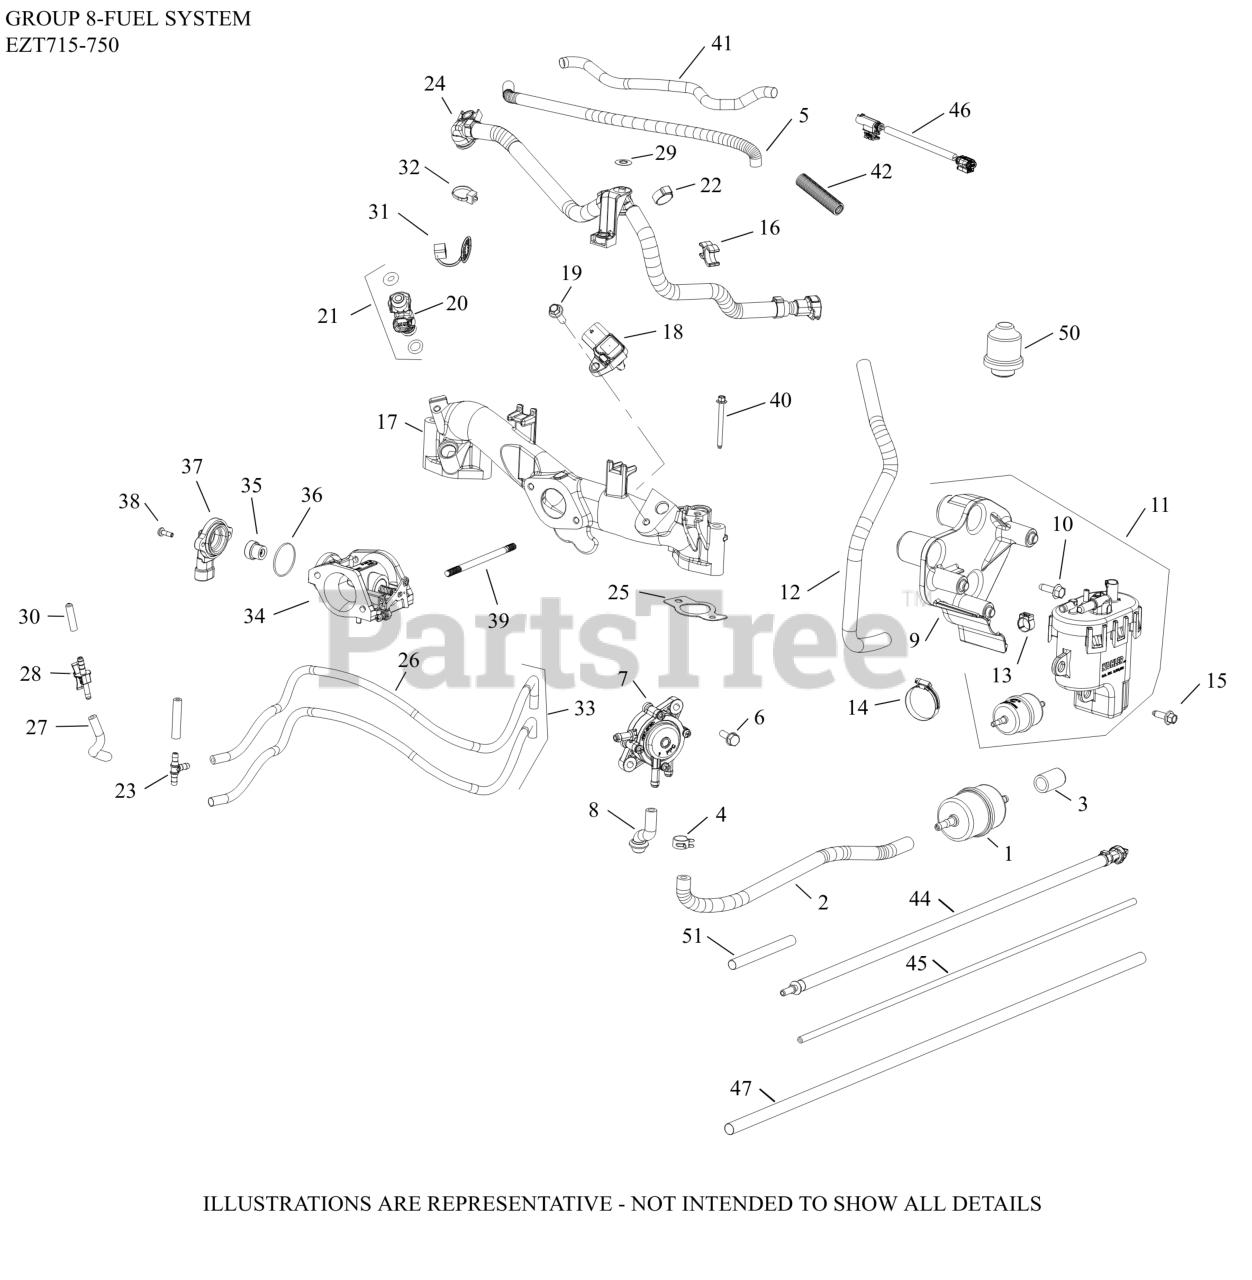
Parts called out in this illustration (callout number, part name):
1	FILTER, FUEL
2	HOSE,LW PERM.FUEL 24.00"-USE 25 111 81-S
3	MASKING CAP
4	SPRING CLAMP, HOSE
5	SLEEVE, ANTI-ABRASION
6	SCREW, TAP M6X1.7X18
7	PUMP, FUEL (PULSE)-(#2539326S)
9	BAFFLE, FUEL MODULE
10	SCREW, THREAD FORMING
11	FUEL PUMP
11	KIT, FPM W/BRCKT(EKT740-750, EZT715-750)
12	SLEEVE, INSULATING
13	CLAMP, OETIKER
14	CLAMP, HOSE (KM)-USE 25 237 31-S
15	SCREW, HEX FLANGE (M6 W/DOG POINT)
16	RETAINER, CLIP
17	MANIFOLD MACHINED (EFI)
18	SENSOR, T-MAP
19	SCREW, FLG M6x1.0x20
20	INJECTOR, FUEL
21	KIT, FUEL INJECTOR O-RING
22	CLAMP, HOSE
23	TEE CONNECTOR
24	FUEL HOSE ASSY(ECV,FCV,EZT,EKT,PCH,PCV)
25	KIT, INTAKE MANIFOLD GASKET
27	HOSE EVAPORATIVE (WALBRO)
28	CONNECTOR, EVAPORATIVE
29	CLIP, RETAINER
30	CAP, MASKING
31	CAP, CONNECTOR
32	TIE, CABLE
33	HOSE, ASSEMBLY
34	BODY ASSEMBLY, THROTTLE W/TPS & TS
35	MAGNET, TPS SENSOR
36	O-RING, TPS SENSOR
37	SENSOR, THROTTLE POSITION
40	SCREW, HEX FLANGE (M6 W/DOG POINT)
